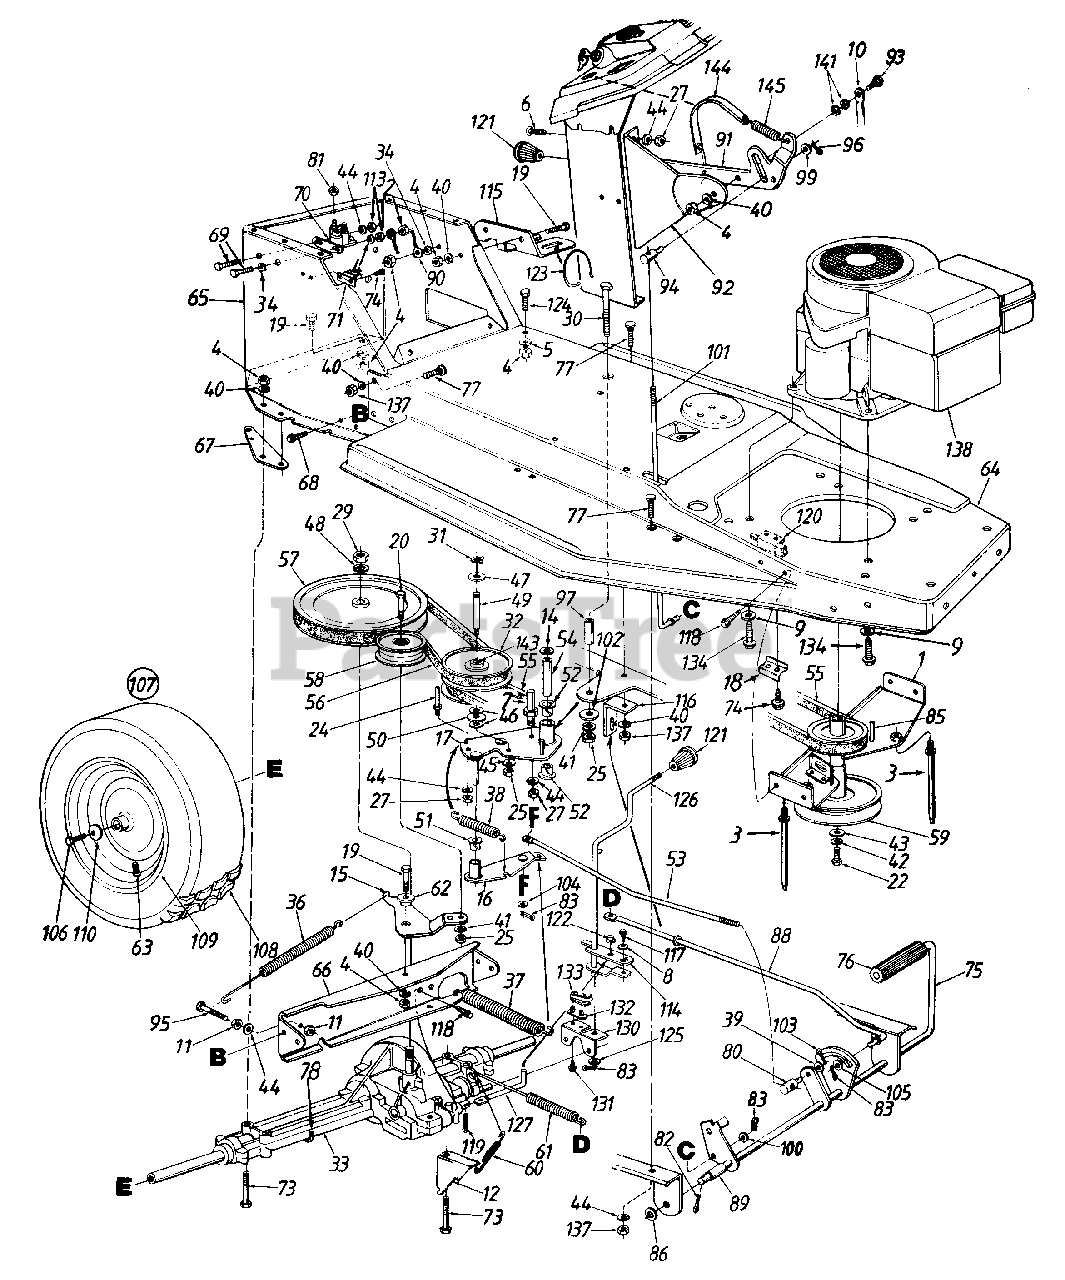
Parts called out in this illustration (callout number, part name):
1	Engine Pulley Belt Guard Ass'y.
2	Hex L-Nut 1/4-20 Thd.
3	Belt Guard Pin 5/16-18 x 4.75" Lg.
4	Hex Nut 5/16-18 Thd.
5	Bell-Wash. .345" I.D. x . 88
6	Truss-Mach. Scr. 1/4-20 x .50"
7	Belt Guard Pin 1/4-20 Thd.
8	Bell-Wash. .265" I.D. x .75
9	Fl-Wash. 3/8" I.D. x .97" O.D.
10	Speed Selector Brace
11	Hex Nut 1/4-28 Thd.
14	Fl-Wash. 3/8" I.D. x 1.26" O.D.
17	Variable Speed Brkt. Ass'y.
18	Switch Plate
19	Hex Bolt 5/16-18 x .75" Lg.
20	Hex Bolt 3/8-24 x 2.0" Lg. Gr. 5
22	Hex Bolt 7/16-20 x 1.5" Lg.
24	Belt Guard Pin
25	Hex Nut 3/8-24 Thd.
27	Hex Nut 1/4-20 Thd.
29	Hex Jam Nut 9/16-18 Thd.
30	Hex Bolt 3/8-24 x 3.75" Lg.
31	Snap Ring
32	Variable Speed Pulley Ass'y.
33	Transaxle Ass'y. Comp.
34	Ext. L-Wash. 5/16" I.D.
36	Extension Spring 6.12" Lg.
37	Extension Spring 6.74" Lg.
38	Extension Spring 2.59" Lg.
39	Fl-Wash. .385" I.D. x .620"
40	L-Wash. 5/16" I.D.
41	L-Wash. 3/8" I.D.
42	L-Wash. 7/16" I.D.
43	Fl-Wash. .450" I.D. x 1.25"
44	L-Wash. 1/4" I.D.
45	Bell-Wash. .39" I.D. x 1.13"
46	Fl-Wash. .56" I.D. x 1.0" O.D.
47	Washer "Teflon" .565 I.D.
48	Bell-Wash. 9/16" I.D. x 1.125" O.D.
49	Shaft .56" Dia. x 3.875" Lg.
50	Thrust Brg. 1.25 O.D.
51	Flanged Nyliner Brg.
52	Nyliner Flanged Brg.
53	Speed Control Rod
54	Spacer
55	V-Belt
56	V-Belt
57	V-Pulley 8" Dia.
58	Idler Pulley 3-1/8" Dia.
59	Dbl. Pulley 6.0" Dia. x 3.56"
60	Extension Spring 3.18" Lg.
61	Extension Spring 7.08" Lg.
62	Shld. Spacer .500" Dia.
63	Air Valve
69	Hex Bolt 1/4-20 x .62" Lg.
70	Solenoid
71	Circuit Breaker
73	Hex Bolt 5/16-18 x 2.75" Lg.
74	Truss Mach. B-Tap Scr. #10 x .50" Lg.
77	Ribbed Neck Bolt 5/16-24 x .84"
78	Spring Anchor
80	Ferrule
81	Hex Sems Nut 1/4-20 Thd.
82	Cot-Pin 1/8" Dia. x 1.25" Lg.
83	Cot-Pin 3/32" Dia. x .75" Lg.
85	Sq. Key 1/4 x 2.0" Lg.
86	Fl-Wash. .635" I.D. x 1.0"
88	Brake Rod
89	Spacer 5/8" I.D. x 1.2" Lg.
90	Ground Wire 7.25" Lg.
91	Speed Selector Lever
92	5 Speed Selector Brkt.
93	Shld. Bolt .437" Dia. x .47" Lg.
94	Ferrule
95	Hex Bolt 1/4-28 x 1.25" Lg.
96	Intern. Cot-Pin 5/16" Dia.
97	Spacer .375" I.D. x .625"
99	Fl-Wash. .344" I.D. x .62"
100	Fl-Wash. .25" I.D. x .62" O.D.
101	Speed Control Rod
102	Fl-Wash. 3/8" I.D. x 1.25" O.D.
103	Cot-Pin 1/8" Dia. x 1.0" Lg.
104	Fl-Wash. .34" I.D. x .68"
105	Fl-Wash. .34" I.D.
106	Hex L-Bolt 5/16-24 x .75" Lg.
110	Bell-Wash. 345" I.D. x .88"
113	Hex Jam Nut 1/4-20 Thd.
114	Shift Lever Adjusting Link
115	Shift Lever Spring Brkt.
118	Hex Wash. Hd. Tap Scr. 1/4-20 x .5" Lg.
119	Intern. Cotter Pin
120	Safety Switch (clutch)
121	Knob
122	Retaining Ring
123	Compression Spring 1.5" Lg.
124	Hex Wash. Hd. Scr. 5/16-18 x 7/8" Lg.
125	Fl-Wash. .469" I.D. x .88"
130	Shift Lever Support
131	Hex Wash. Hd. #8 x .50" Lg.
132	Insulator Nut Plate
133	Spring Switch
134	Hex Tap Scr. 3/8-16 x 1.25"
137	Hex Nut 5/16-24 Thd.
138	Engine
141	Wave Wash. .445" I.D.
143	Needle Brg.
144	7-Speed Indicator Strip
145	Ext. Spring 2.04" Lg.
